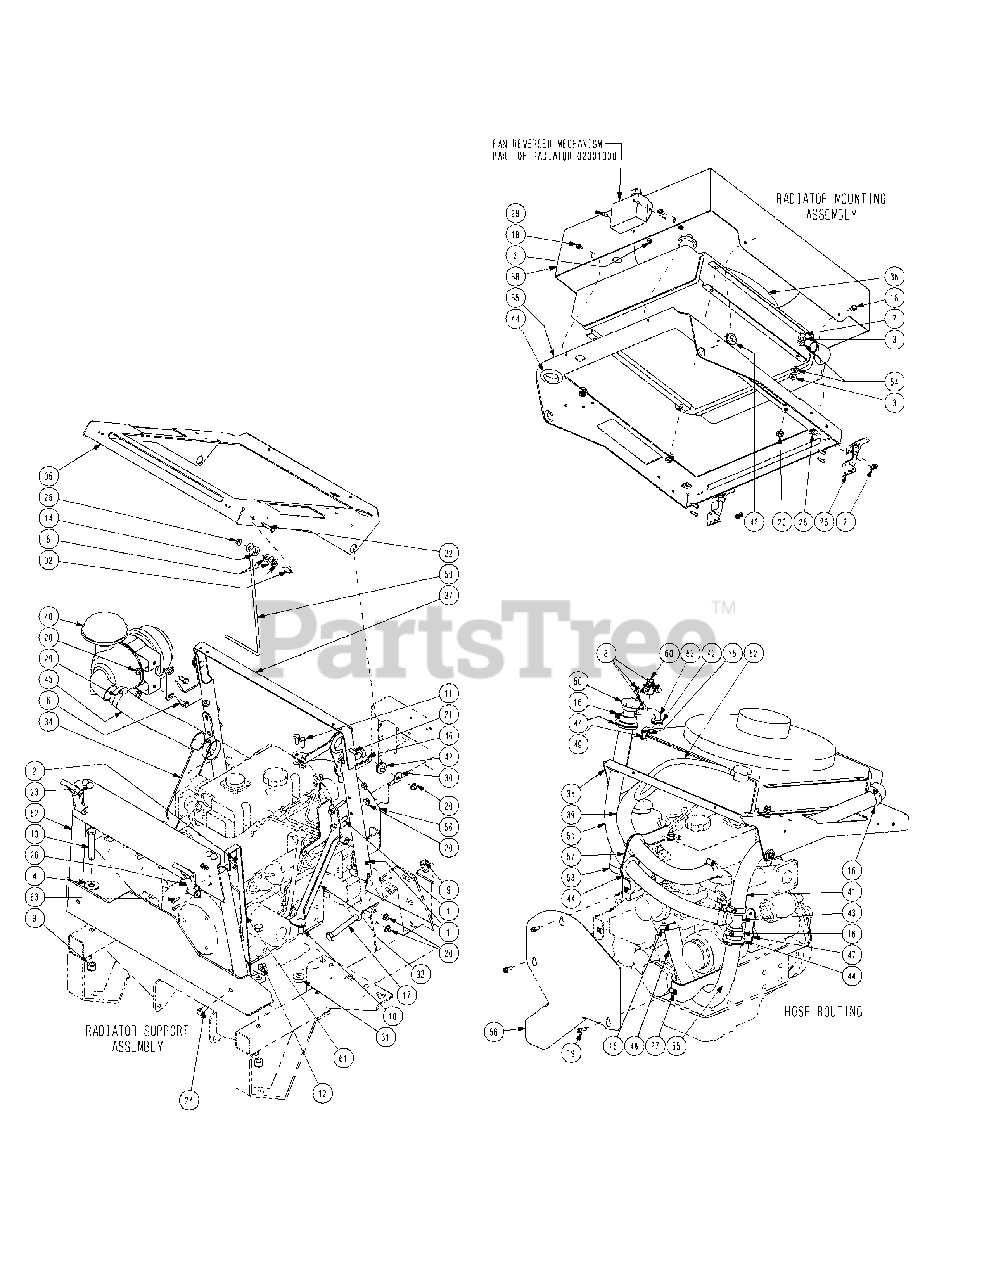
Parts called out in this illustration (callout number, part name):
1	Hex Cap Screw, 5/16-18 x 1.75
2	Nut, 10-24, Nylon Insert
3	Flat Washer, 5/16
4	Flat Washer, 1/2
5	Flat Washer, 3/8
6	Hex Cap Screw, 5/16-18 x 3/4
7	Hex Head Cap Screw, 5/16-18 x 1.00
8	Hose Clamp
9	Nut, 1/2-13, Nylon Insert
10	Hex Cap Screw, 1/2-13 x 1.00
11	Hex Cap Screw, M8-1.25 x 18mm
12	Hex Nut, 3/8-16 Flange Lock
13	Hex Head Cap Screw, 1/2-13 x 3.00
14	Spacer, Control Rod
15	Hose Clamp, 1/4-5/8
16	Hose Clamp,, 7/8:1-1/4
17	Hex Cap Screw, 1/2-13 x 3.50
18	Screw, TT, 1/4-20, 0.5, Hex Index Washer
19	Screw, TT, 1/4-20, 0.75, Hex Index Washer
20	Hexflange Lock Nut, 5/16-18
21	Carriage Bolt, 5/16-18 x 1.00
22	Hex Cap Screw, 1/4-20 x 1.25
23	Rubber Bumper, .62 OD x .22 Thick
24	Hex Cap Screw, 3/8-16 x .750
25	Lock Nut, 1/4-20
26	T-Handle Latch Draw
27	U-Nut, 1/4-20
28	Hex Cap Screw, 10-24 x 1/2
29	Hose Clamp
30	Washer, 5/16 x 1.06
31	Nut, 1/2-13, FlangeLock
32	Spacer, .259 x .375 x .707
33	Radiator Support Gusset, RH
34	Radiator Support Gusset, LH
35	Radiator Mounting Bracket
36	Radiator includes:
37	Radiator Mounting Assembly
38	Radiator Shroud Assembly
39	Radiator Hose, 1.12 ID x 36" Long
40	Air Filter Assy includes:
41	Radiator Hose 1.12 x 22.5" Long
42	Gromment, .62 ID x 1.13 OD
43	Tee Adaptor
44	Gromment, 1.5 ID x 2.13 OD
45	Air Hose, 1.75 ID
46	Spacer, .625 OD x .407 ID x .375
47	Radiator Hose Bracket
48	Radiator Hose, 1.12 ID x 18" Long
49	Elbow Adaptor, 1/8 NPT x 1/4
50	Neck Filler Adaptor
51	Radiator Hose, 1" ID x 28.5" Long
52	Radiator Hose, 1/4" x 27"
53	Radiator Hose, 1/4" x 9"
54	Flat Rubber Washer, 1/4
55	Belt Shield Bracket
56	Belt Shield
57	Radiator Hose Bracket
58	Over Flow Coolant Container
59	Radiator Stand
61	Radiator Support Bracket
62	Radiator Mounting Assembly
63	Hex Cap Screw, 10-24 x 3/4
